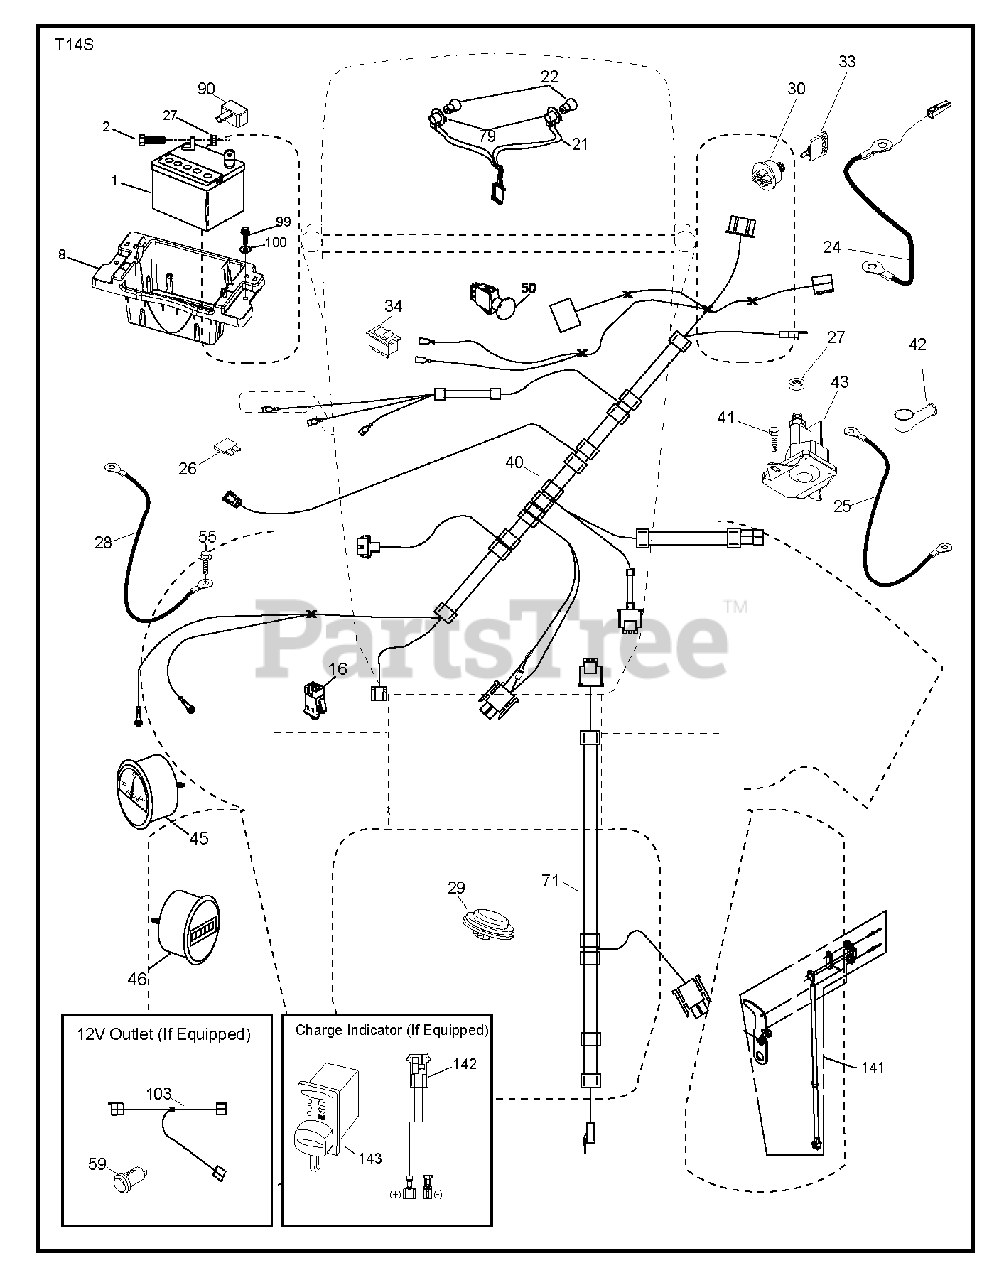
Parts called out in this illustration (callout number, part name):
1	Battery, Dry 30 Amp
2	BOLT.HEX.1/4.X.3/4.DICHROMATE
8	TRAY.BATTERY BOX.FRONT
16	SWITCH INTERLOOK PUSH-IN
21	HARNESS.LIGHT W/4152J BULBS
24	CABLE.FRBATT.W/WIRE.8GA.8
25	CABLE.STARTER.8GA.17.5
26	FUSE 20AMP
27	NUT
28	CABLE.GROUND.21"BLK.8GA.90T
29	SWITCH.SEAT.DELTA.OPC.
30	SWITCH.IGN.DELTA.W.LGH.ROS
33	KEY.CHAIN.BLISTER.PACK.GEN.USA
40	HARNESS.IGN.DSH.W112V.WPORTWIR
41	SCREW
42	TERMINAL COVER
43	SOLENOID.W/BRASS.PLUNGER
45	GAUGE.AMMETER.SILVER/WHITE
46	GAUGE.HOUR.METER.SILVER/WHITE
50	RB PTO.SWITCH.8 TERMINAL.BLACK
55	SCREW 5/16"
71	HARNESS-CHASSIS SUB
79	BULB HOLDER ASM.
90	COVER.TERMINAL.BATTERY
99	SCREW HEXWSHR 1/4-20X3/4
141	KIT.G700/G730.ROS 71750
